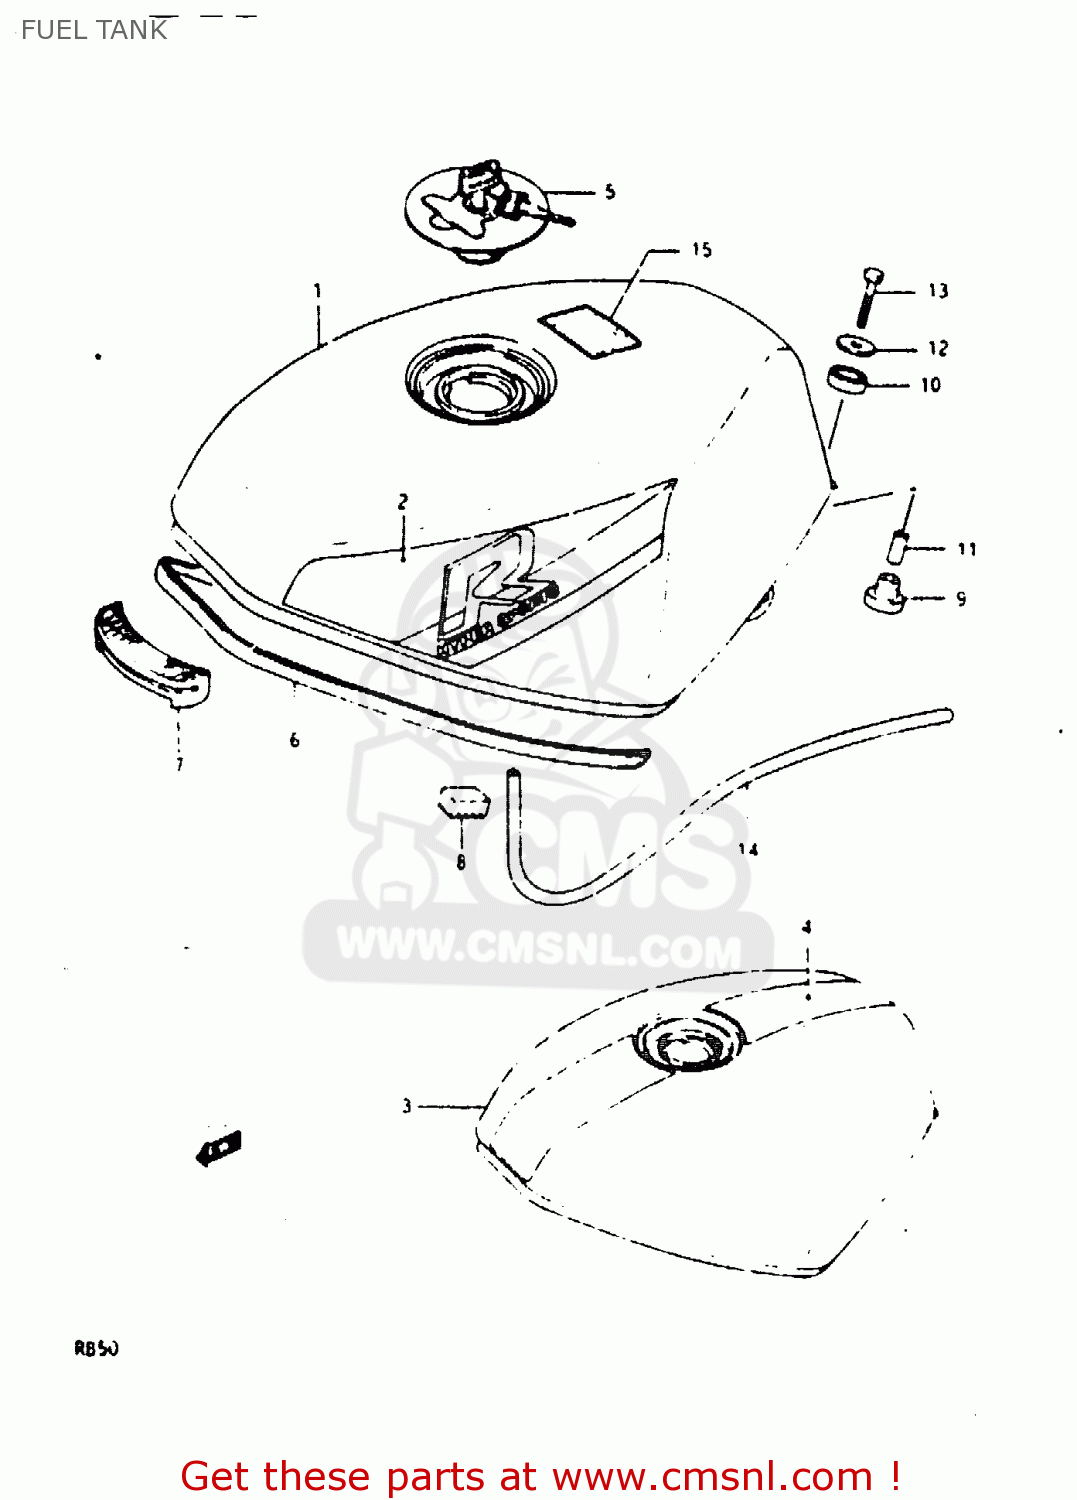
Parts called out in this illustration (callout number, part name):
1	TANK ASSEMBLY,FUEL
5	CAP SET,FUEL TANK
6	MOLDING,FUEL TANK
7	CUSHION,FUEL TANK FR
8	CUSHION,FUEL TANK SIDE
9	CUSHION
10	CUSHION
11	SPACER (6.4X9X19)
12	WASHER (6.5X24X1.6)
13	BOLT
14	HOSE,FUEL
15	LABEL
